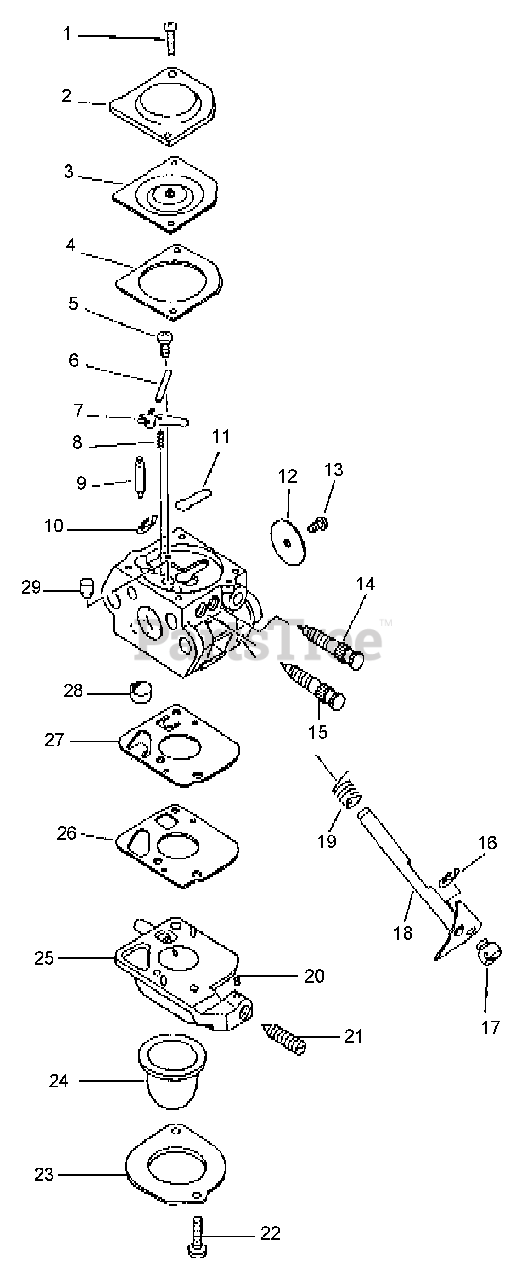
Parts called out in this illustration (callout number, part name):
1	SCREW
2	COVER, METERING
3	DIAPHRAGM, METERING
4	GASKET, METERING
5	SCREW, METERING LEVER PIN
6	PIN, METERING LEVER
7	LEVER, METERING
8	SPRING, METERING LEVER
9	VALVE, NEEDLE
10	RING, RETAINING
11	PLUG, WELCH
12	VALVE, THROTTLE
13	SCREW
14	NEEDLE - LOW SPEED
15	NEEDLE - HIGH SPEED
16	RING, RETAINING
17	SWIVEL
18	SHAFT, THROTTLE
19	SPRING, RETURN
20	PIECE, FRICTION
21	SCREW, IDLE ADJUST
22	SCREW, RETAINER
23	RETAINER, PURGE BULB
24	BULB, PURGE
25	BASE, PURGE
26	GASKET, PUMP
27	DIAPHRAGM, PUMP
28	STRAINER
29	NOZZLE, CHECK VALVE
